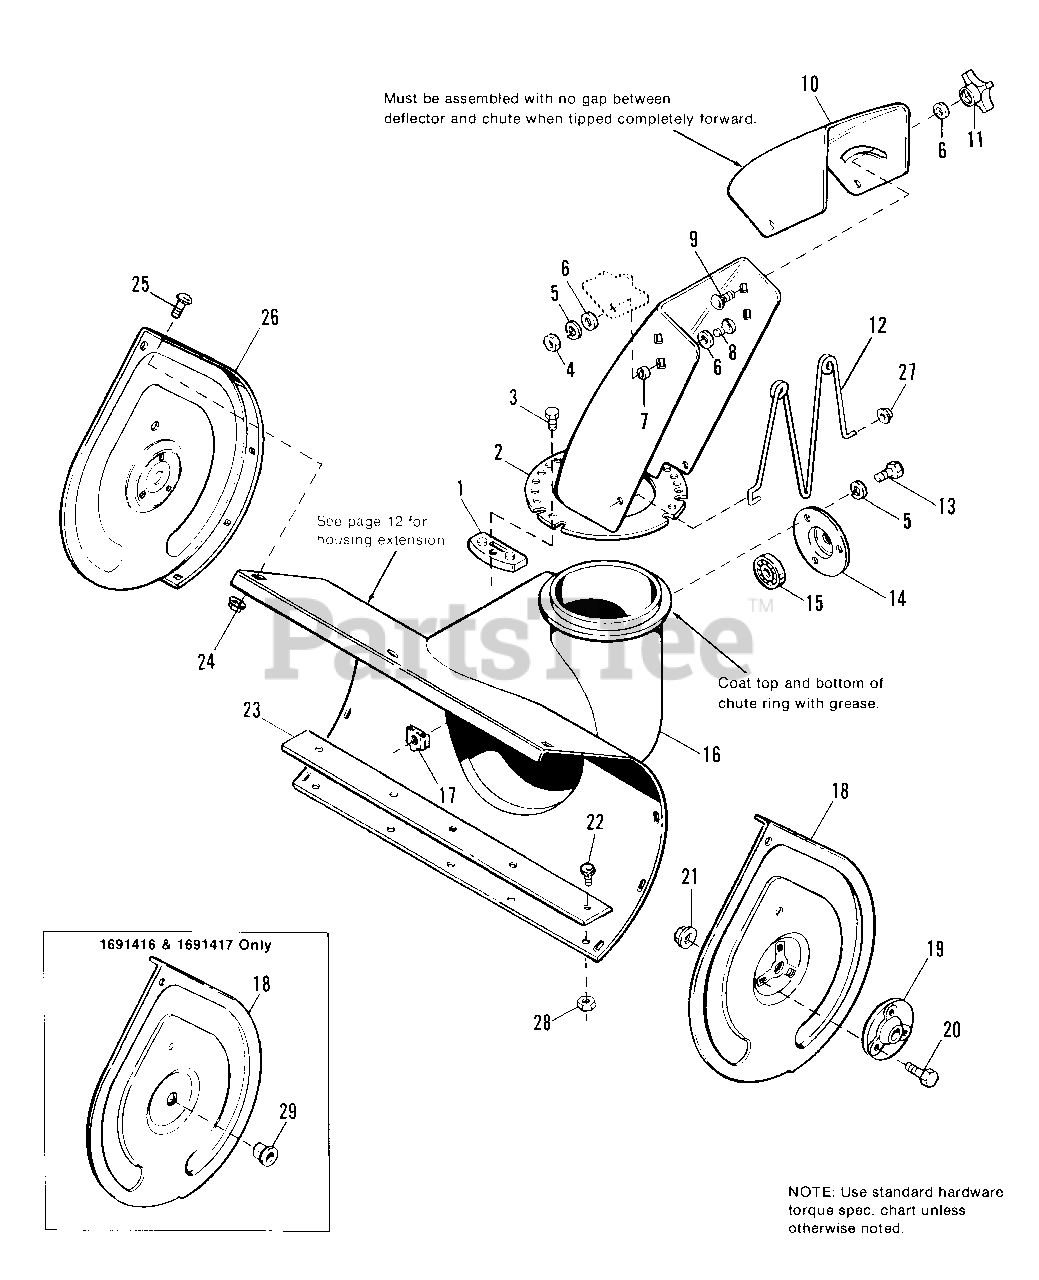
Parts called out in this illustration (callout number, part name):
1	HOLD DOWN, Chute
2	CHUTE ASSY.
3	SCREW, Plastite, #10
4	NUT, Hex, 5/16-18
5	LOCKWASHER
6	WASHER, 5/16
8	SCREW, Truss Hd., 5/16-18 x 3/4
9	BOLT, Carriage, 5/16-18 x 7/8
11	KNOB, Deflector Adj.
12	GUARD, Chute
13	SCREW, Hex, 5/16-18 x 5/8
14	RETAINER, Bearing
15	BEARING, Ball, Auger Hsg. Assy.
16	AUGER HSG. ASSY.
17	NUT, Retainer, 5/16-18
18	AUGER HSG. END, L.H. (1691172, 1691364 only)
18	AUGER HSG. END, L.H. (1691416 & 1691417 only)
19	BEARING, Auger (1691172, 1691364 only)
20	SCREW, Hex, Whizlock, 5/16-18 x 3/4 (1691172, 1691364 only)
21	NUT, Hex, Fl. Hd. Lock, 5/16-18 (1691172, 1691364 only)
22	BOLT, Carriage, 1/4-20 x 5/8
23	SCRAPER BLADE, Auger Hsg. Assy.
24	NUT, Hex, 1/4-20 Fl. Lock
25	BOLT, Carriage, 1/4-20 x 1/2
26	AUGER HSG. END., R.H. (1691172, 1691364 only)
28	NUT, Hex Whizlock, 1/4-20
29	BUSHING (1691416 & 1691417 only)
